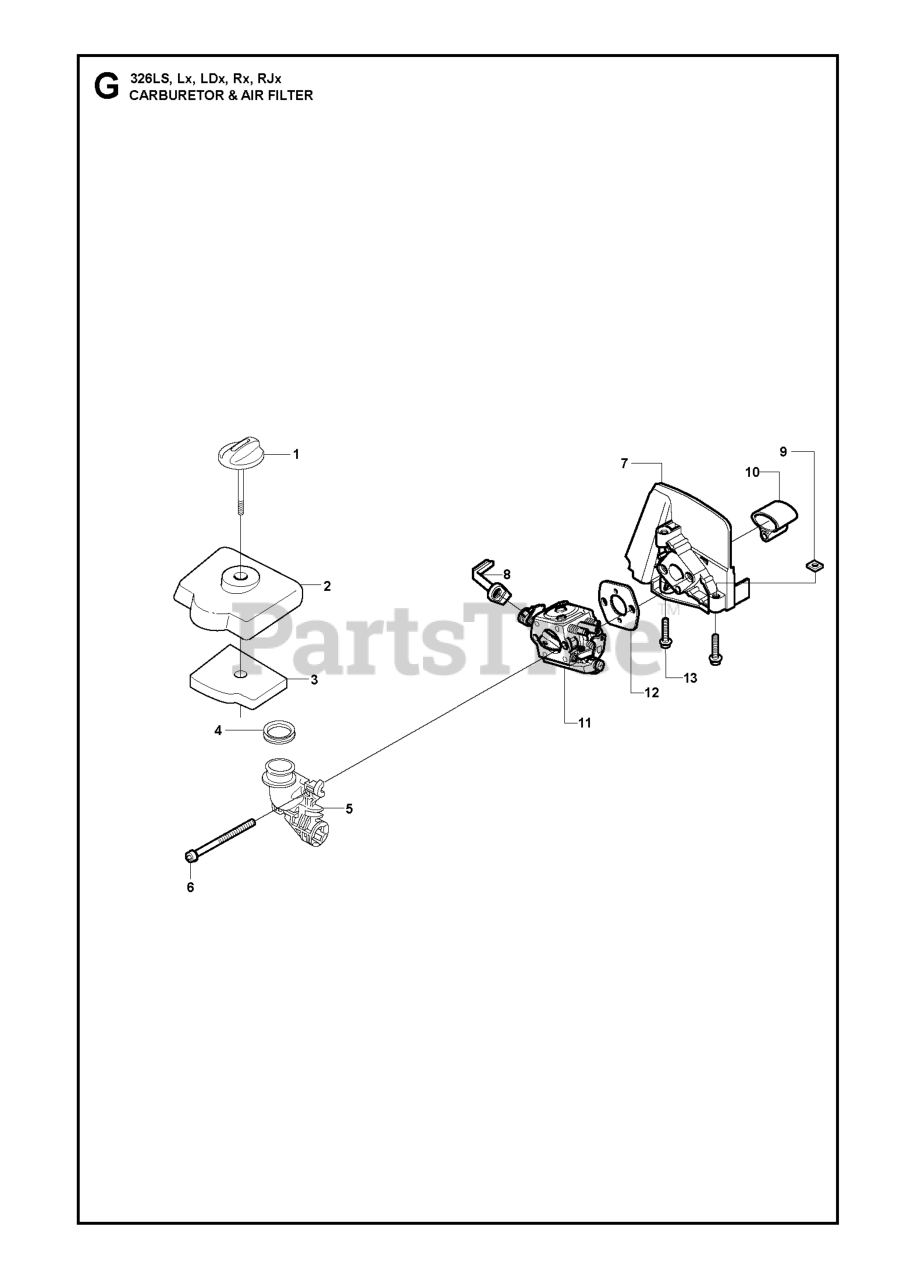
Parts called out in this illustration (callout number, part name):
2	FILTER COVER
3	AIR FILTER
8	CHOKE CONTROL
11	CARBURETOR
